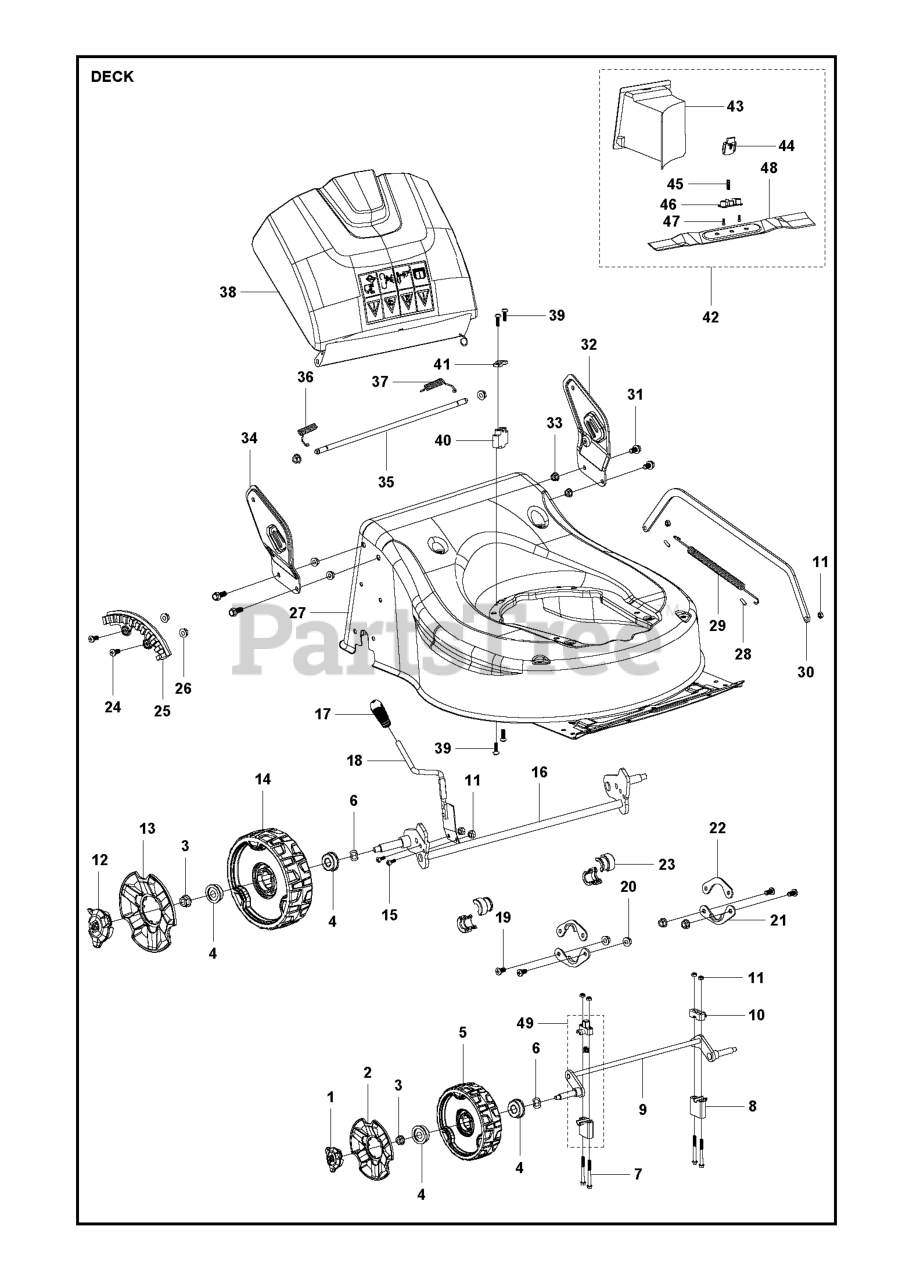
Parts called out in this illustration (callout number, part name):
1	WHEEL COVER 6" #25340700101
2	COVER 7 WHEEL COVER
3	LOCKING BOLT M8,GB6187.1 #2680
5	WHEEL ASSY 7 WHEEL
6	WASHER Ï?12 #26800706202
9	FRONT AXLE ASSY
11	LOCKING BOLT M6,GB889.1 #26800
12	WHEEL COVER 8" #25341000101
13	WHEEL COVER 8" #25341100101
14	WHEEL #25341300101
15	WASHER M6*14 #26800203001
16	REAR AXLE ASSY
17	KNOB HEIGHT ADJUSTMENT #25341
18	HANDLE ASSY
19	SCREW M6*16 #26800204601
20	LOCK NUT M6,GB/T6187.1-2000 #2
21	FIXING PLATE #26300124401
22	FIXING PLATE #26300314601
23	COVER AXLE #25235300101
25	SEGMENT #25214200102
28	TUBING #29000300101
29	SPRING #26801103903
30	CONNECTING ROD
31	BOLT M8*16 #26800606401
32	BRACKET LEFT
34	BRACKET RH
36	SPRING #26801125501
37	BRACKET #26801125401
38	COVER REAR FLAP
43	PLUG 25232600101
48	BLADE 26300349801
